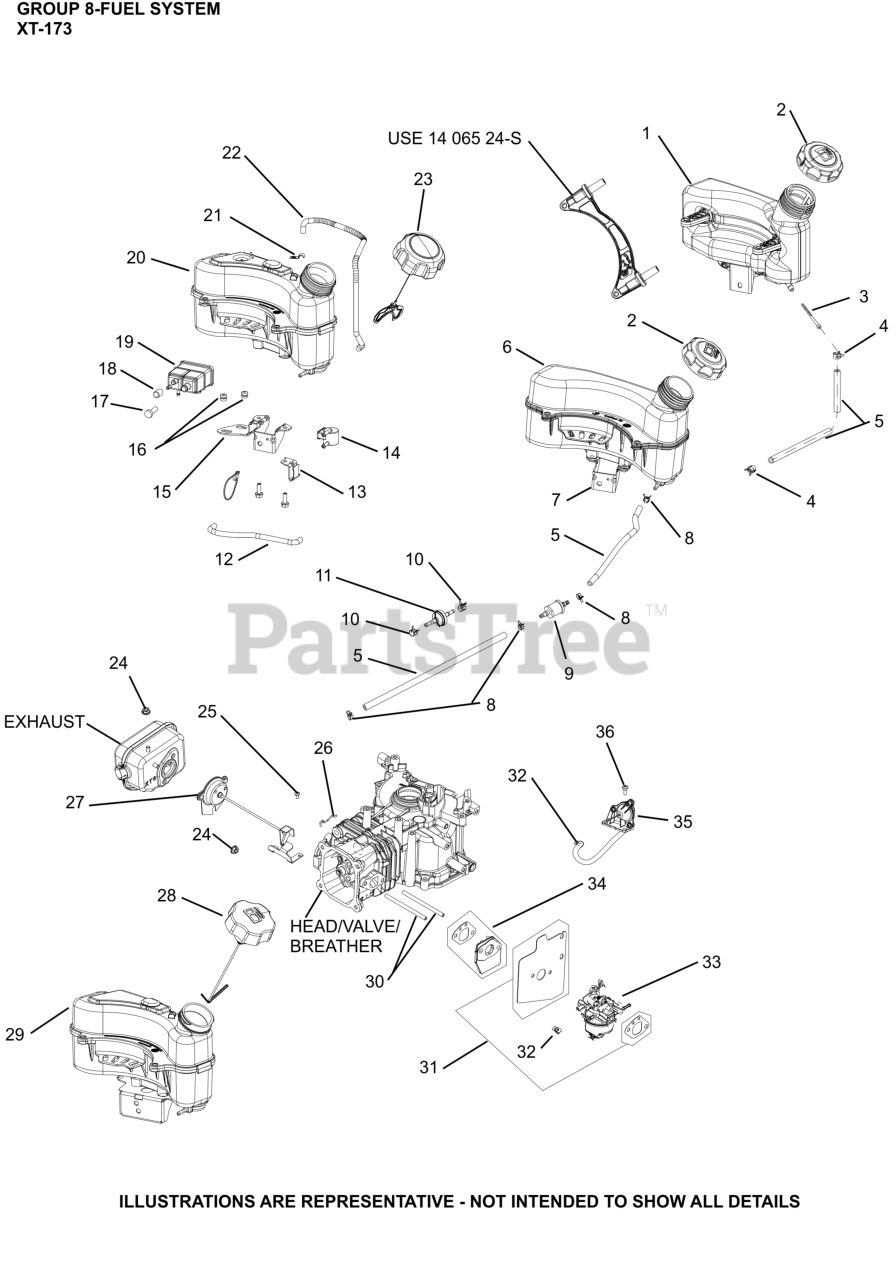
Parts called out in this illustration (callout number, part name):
1	KIT, TANK ASSY, NON-CALIFORNIA
2	CAP, FUEL ASSEMBLY-USE 14 227 11-S
3	FILTER, FUEL IN-NIPPLE
4	CLAMP, HOSE
5	HOSE,LW PERM.FUEL 24.00"-USE 25 111 81-S
25	SCREW, M4 THRD FRMNG-(#25086439S)
26	LINKAGE, AUTO CHOKE
31	GASKET, CARBURETOR - USE 14 041 24-S
32	CLAMP, HOSE
33	KIT, CARB W/GASKETS - USE 14 853 41-S
35	DIAPHRAGM, ASSEMBLY
36	SCREW, SHOULDER-(#25086440S)
NI	GASKET SPACER
NI	STUD, M6X1.0X93.8MM
NI	KIT, SPACER W/GASKET
NI	PLATE, CHOKE
NI	KIT, HIGH ALT (4000-8000 FT)
NI	KIT, HIGH ALTITUDE (ABOVE 8,000 FT.)
NI	KIT, CARB REPAIR - USE 14 757 03-S
